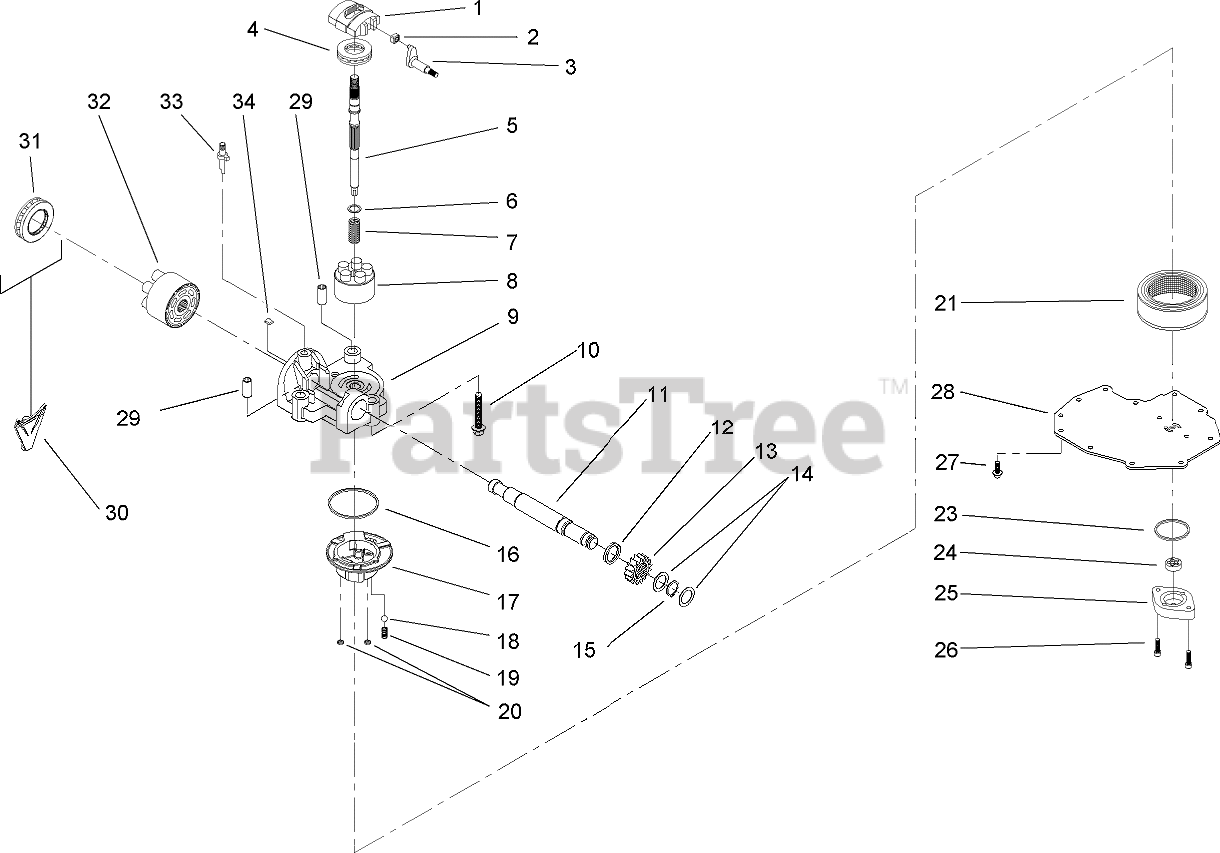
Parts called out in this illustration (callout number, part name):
1	SWASHPLATE-VARIABLE
2	GUIDE-SLOT
3	TRUNNION ASM
4	BEARING-THRUST
5	SHAFT-INPUT
6	WASHER-THRUST
7	SPRING-BLOCK
8	CYLINDER BLOCK ASM
9	CENTER SECTION KIT
11	SHAFT-OUTPUT
12	SPACER
13	GEAR-PINION, 16T
14	WASHER
15	RING-RETAINING
16	O-RING
17	BEARING
18	BALL
19	SPRING-RELIEF
20	O-RING
21	FILTER
22	SEALANT
23	O-RING
24	GEROTOR ASM
25	COVER-GEROTOR
26	CAPSCREW
28	COVER-LOWER
30	RETAINER-BEARING, MOTOR
31	BEARING-THRUST
32	CYLINDER BLOCK ASM
33	ACTUATOR-BYPASS
34	PLATE-BYPASS
